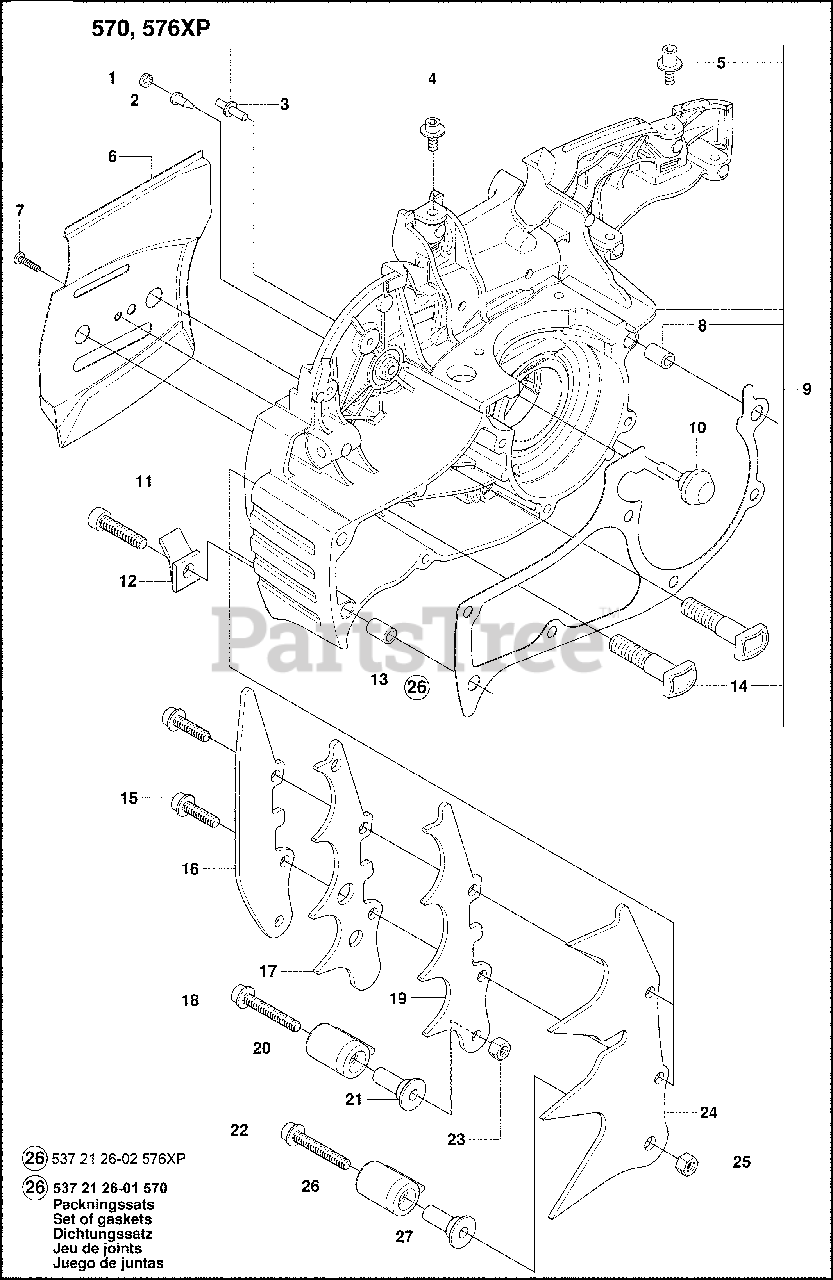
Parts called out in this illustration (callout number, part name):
1	Sintered Filter, Bronze
2	Valve Check, Duckbill
8	Guide Bushing
9	RP CRANKCASE ASSEMBLY
9	CRANKCASE ASSY
12	Chain Catcher
13	Guide Bushing
17	Felling Dog
19	Felling Dog
21	Chain Catcher
22	Screw, Ihscfm
24	Felling Dog
26	Gasket Set
26	Gasket Kit
